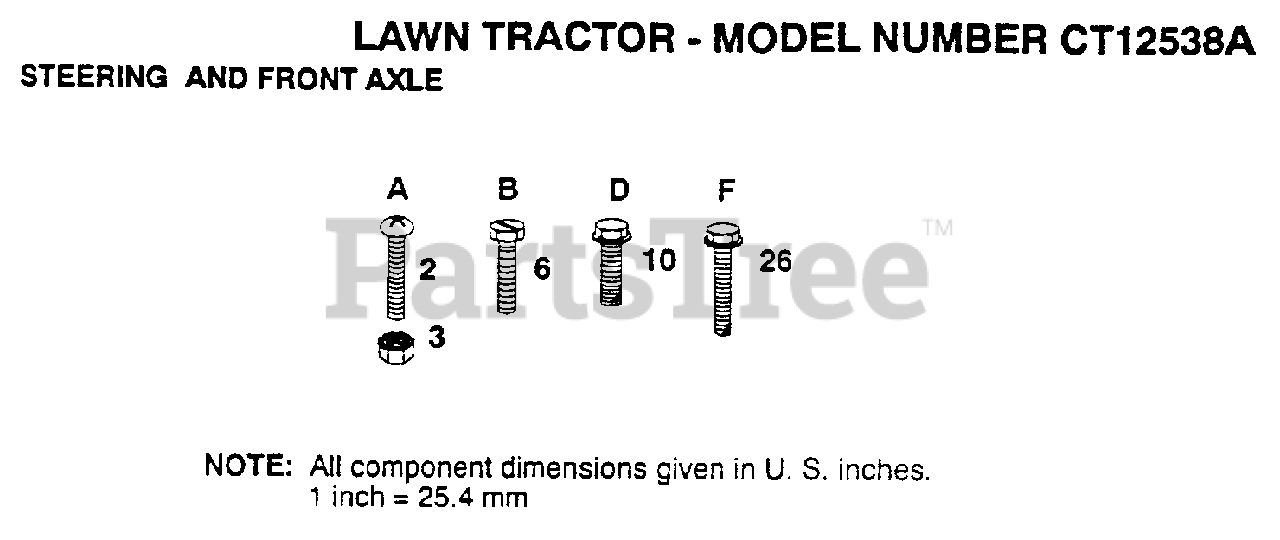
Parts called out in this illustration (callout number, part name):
2	SCREW
6	SCREW LT
10	SCREW LT
26	SCREW
